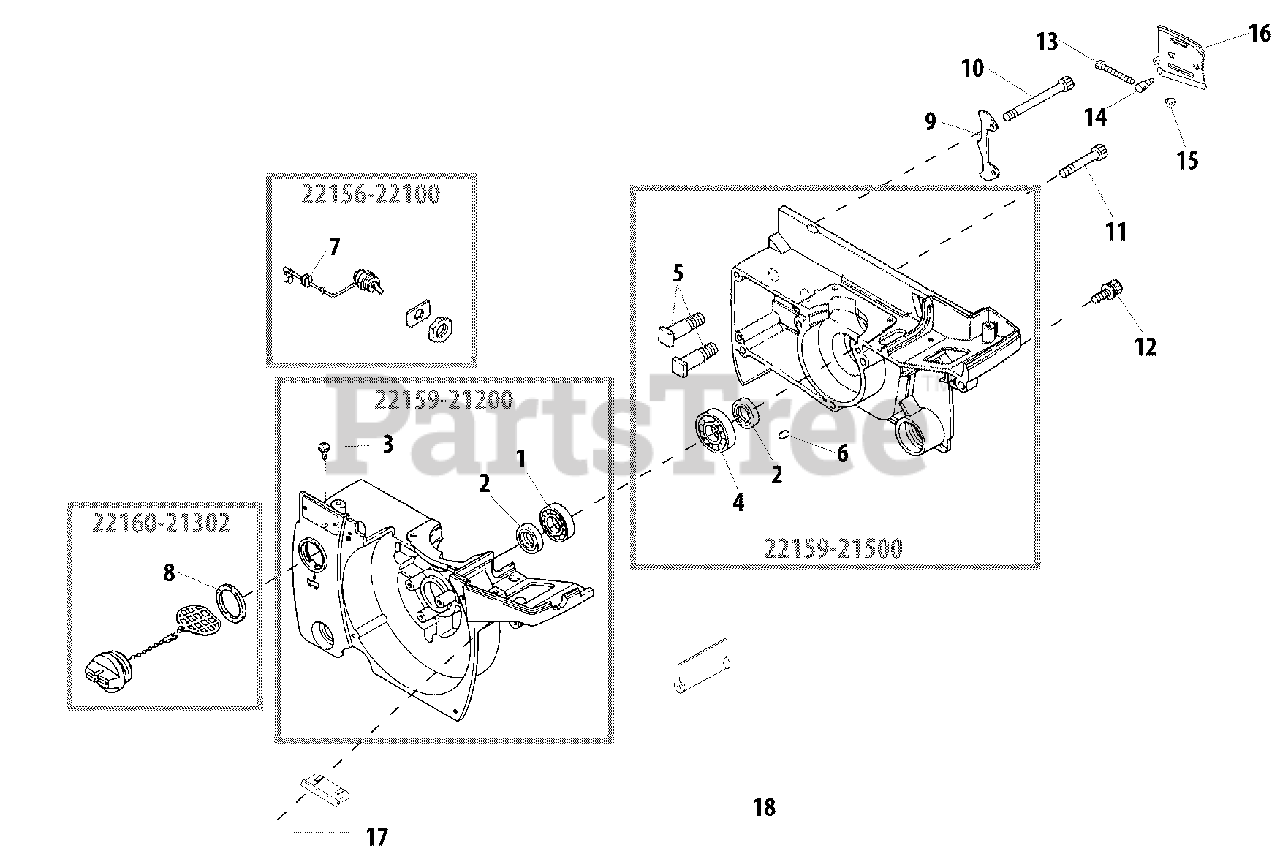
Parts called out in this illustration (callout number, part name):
1	BEARING, BALL - 6001C3
2	SEAL, OIL
3	VALVE, OIL
4	BEARING, BALL - 6201C3
5	BOLT, BAR
6	PIN - LOCATING
8	GASKET
9	SPIKE
10	SCREW - 5X45
11	SCREW - 5X30
12	SCREW - 5X18
13	SCREW, ADJUST
14	TENSIONER, CHAIN
15	NUT
16	PLATE, GUIDE - INNER
17	STOPPER
22156-22100	IGNITION SWITCH ASSY
22159-21200	CRANKCASE ASSY - LEFT
22159-21500	CRANKCASE ASSY - RIGHT
22160-21302	CAP ASSY
